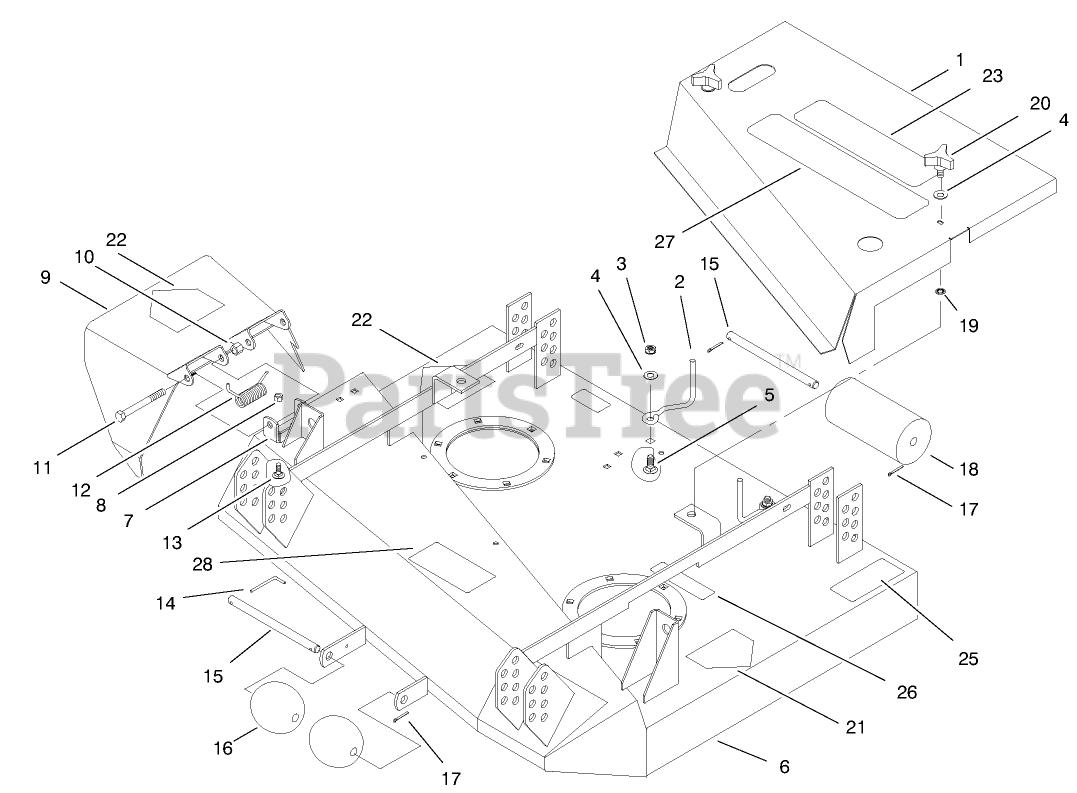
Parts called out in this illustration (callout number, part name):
1	Cover ASM
2	ROD-BELT
3	NUT-HF
4	WASHER-FLAT
5	SCREW-CARR
6	Deck ASM
7	BRACKET-PIVOT
8	NUT-LOCK, CONE
9	Deflector-Grass
10	NUT-HEX
11	SCREW-HH
12	SPRING
13	SCREW-CARR
14	PIN-SPECIAL
15	SHAFT-ROLLER
16	ROLLER
17	PIN-COTTER
18	ROLLER-DECK
19	RING-RETAINING
21	DECAL-DANGER
22	DECAL-DANGER
23	DECAL-PROLINE
25	DECAL-TORQUE
26	DECAL-DANGER
27	DECAL-36"
28	DECAL-DANGER, THROWN OBJECT
